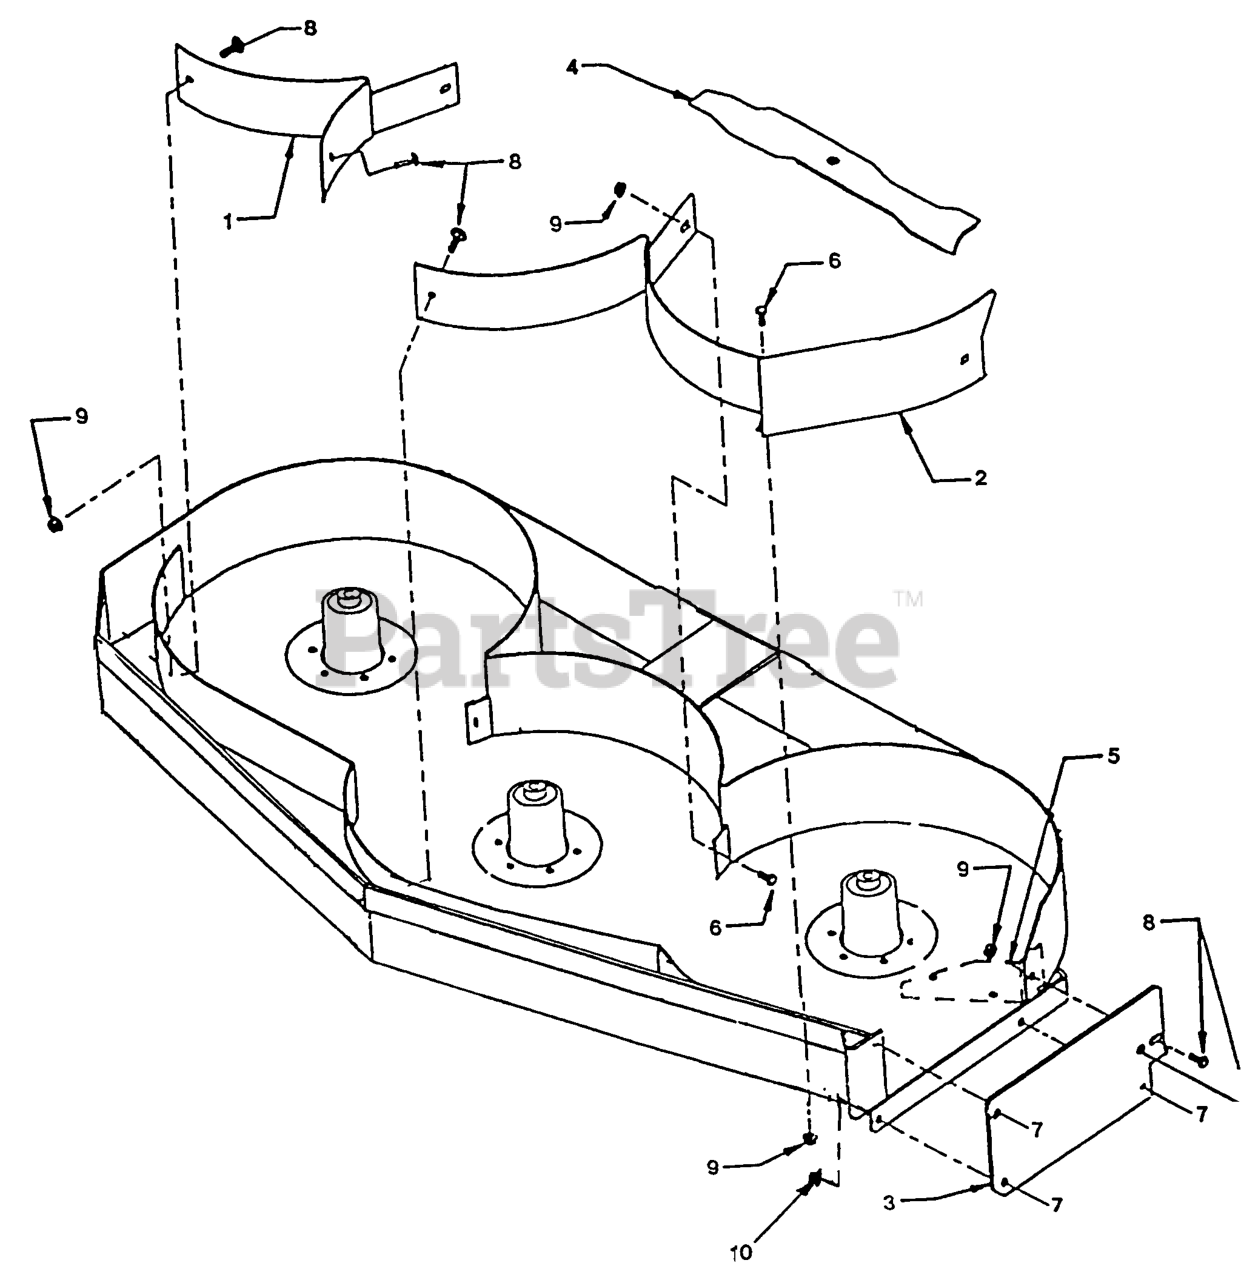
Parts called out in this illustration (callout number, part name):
1	WLD,BAFFLE LH MULCH
2	WLD,RH MULCH BAFFLE
3	PLATE-MULCH COVER
5	BAFFLE-DOGLEG
